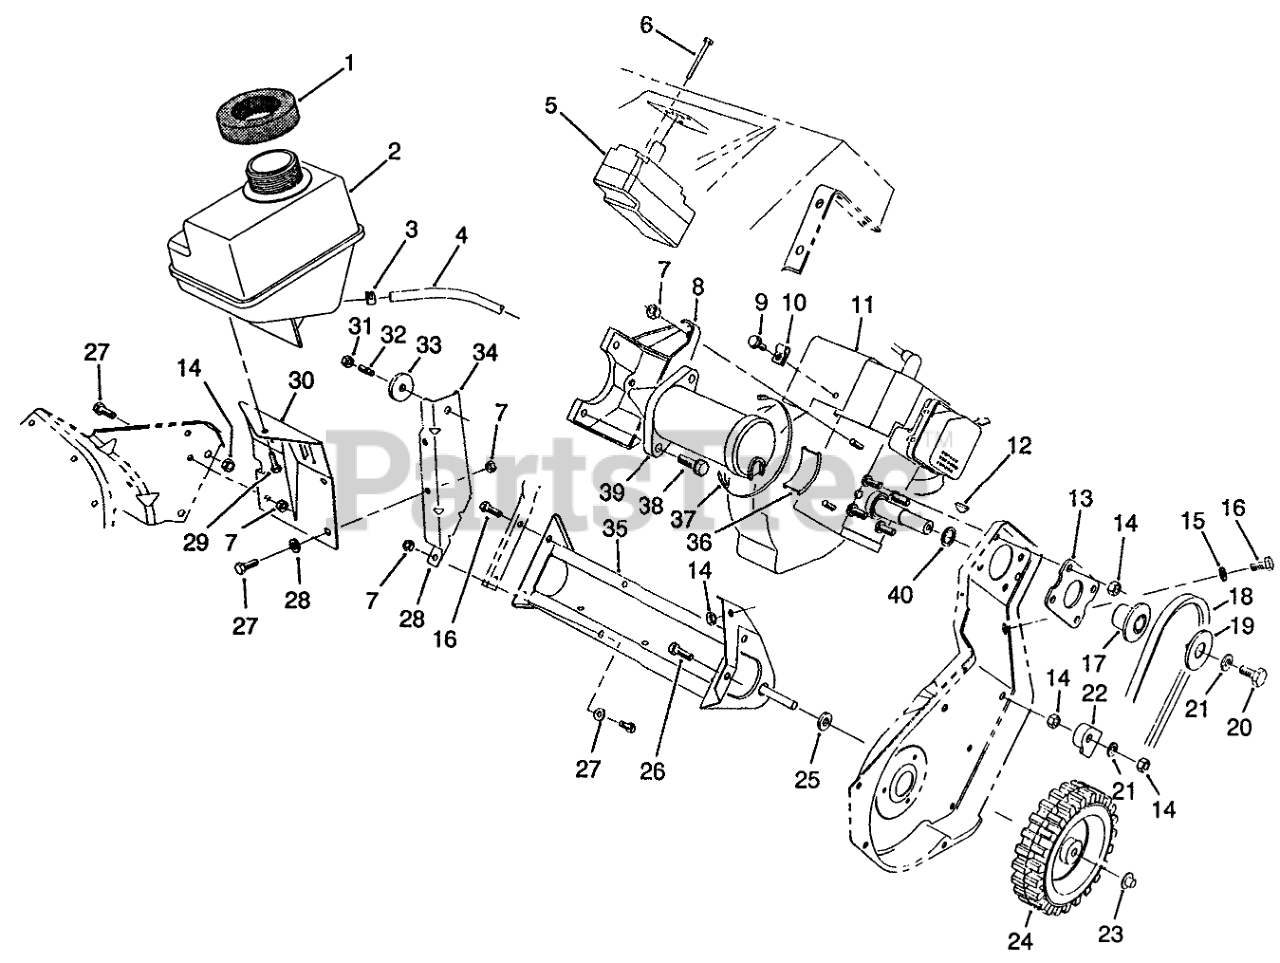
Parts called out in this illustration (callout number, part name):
1	SEAL-FOAM
2	Tank-Gas
3	Clamp
4	LINE-FUEL
5	Starter Switch Assembly
6	SCREW-PLASTITE
7	NUT-LOCK, NI
8	MOTOR MTG BRKT
9	SCREW-HWH
10	CABLE CLAMP
12	KEY-WOODRUFF
13	Plate Engine
14	NUT-LOCK, NI
15	WASHER-PLAIN
16	SCREW-HH
17	Hub-HALF SHEAVE
18	Belt-Drive
19	CAP-HALF SHEAVE
20	SCREW-HH
21	WASHER-FLAT
22	Guide-Cable
23	RETAINER-PUSH ON
24	WHEEL
25	SPACER-PLASTIC
26	SCREW-HH
27	SCREW-HH
28	WASHER-FLAT
29	SCREW-SHWH, THREAD FORMING
30	Bracket-Fuel Tank
31	NUT-LOCK, CONE
33	WASHER-SUPPORT, ENGINE
34	Support-Engine
35	Frame Assembly
36	RR MOTOR SUPPORT
37	TIE-CABLE
38	SCREW-FLOW, TAPTITE
39	Starter Motor Assembly
40	WASHER
